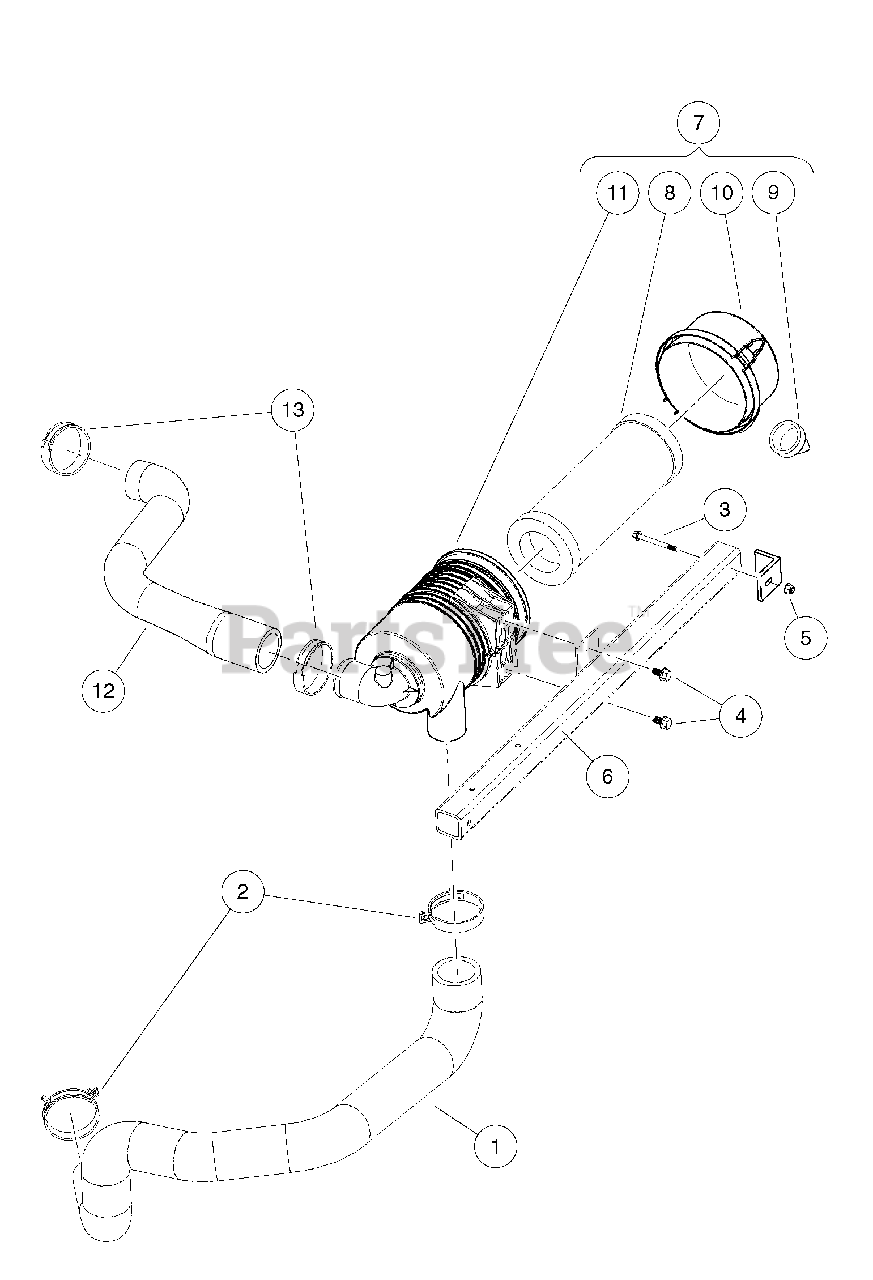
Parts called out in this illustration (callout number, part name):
1	Hose, Intake, Primary
2	Clamp, Hose, Ctb 64mm
3	Bolt, M 6 X 1.0 X 65 Hex, Flange, Head, Black
4	Bolt Flanged Head, M8 X1.25x 16 with Loctite
5	Nut Flg, M6 X 1.0 Nylon
6	Weldment, Support, Air Cleaner
7	Filter, Air, Canister, W/labe
8	Element, Filter, Air, 5 In
9	Valve, Evacuator, Filter Air
10	Cap, Latch Lock, Filter, Air
11	Body, Canister, Filter, Air
12	Intake Awd Hose Gas
13	Clamp, Worm Screw, Hose, 2"
